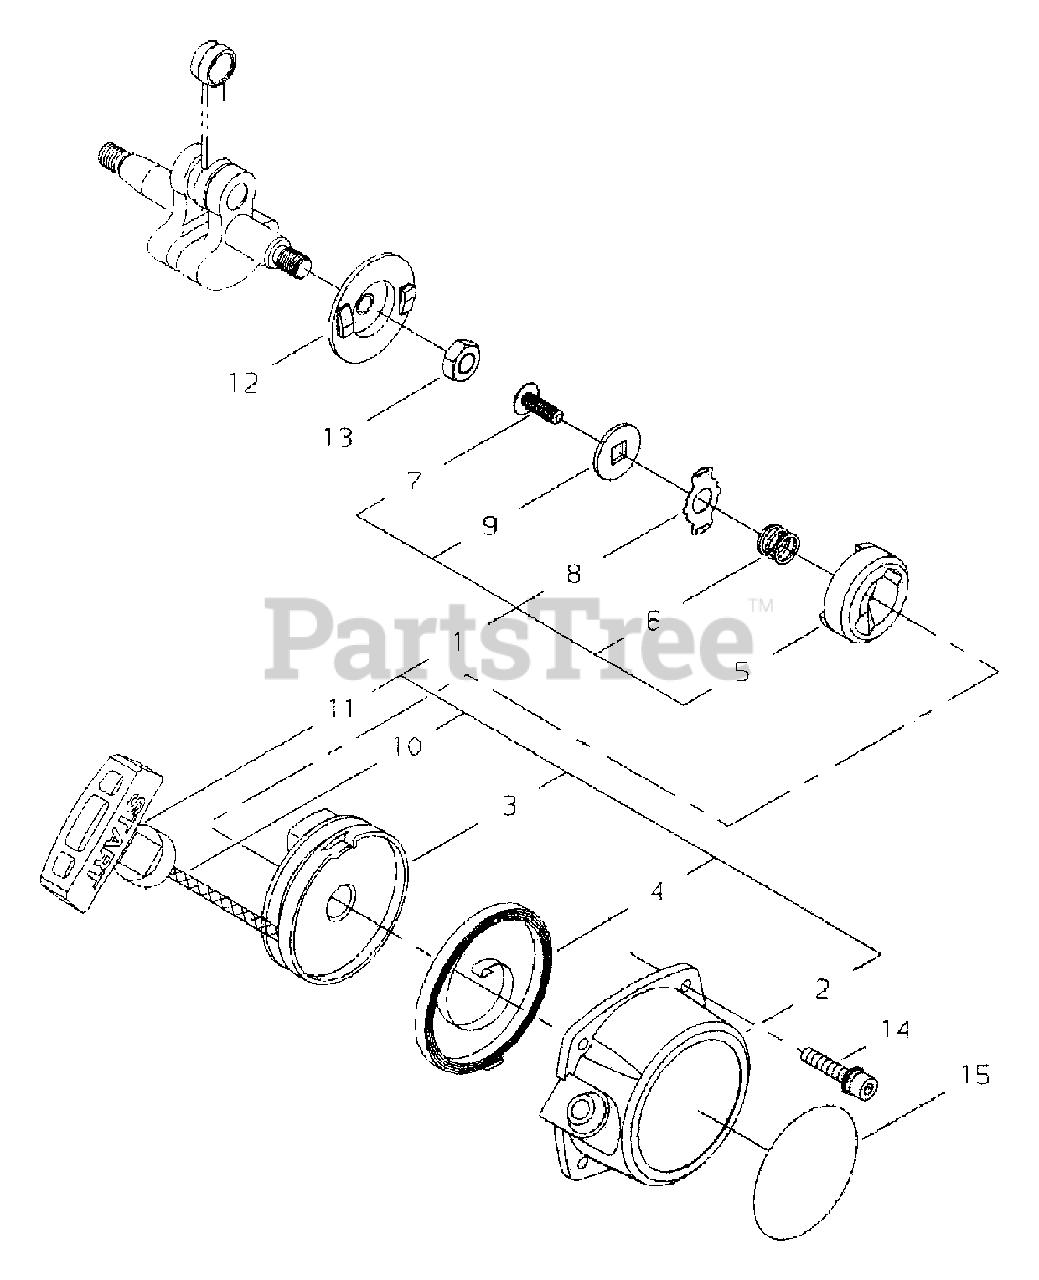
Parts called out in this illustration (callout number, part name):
1	STARTER ASSY, RECOIL
2	CASE, RECOIL STARTER
3	REEL, ROPE
4	SPRING, RECOIL
5	RATCHET
6	WASHER, WAVE
7	SCREW 5 MM
8	RETAINER
9	WASHER 5 MM
10	ROPE, STARTER
11	GRIP, STARTER
12	PULLEY, STARTER
13	NUT M8×1
14	BOLT, ADHESIVE M4×16
15	LABEL, SHINDAIWA PROFESSIONAL
